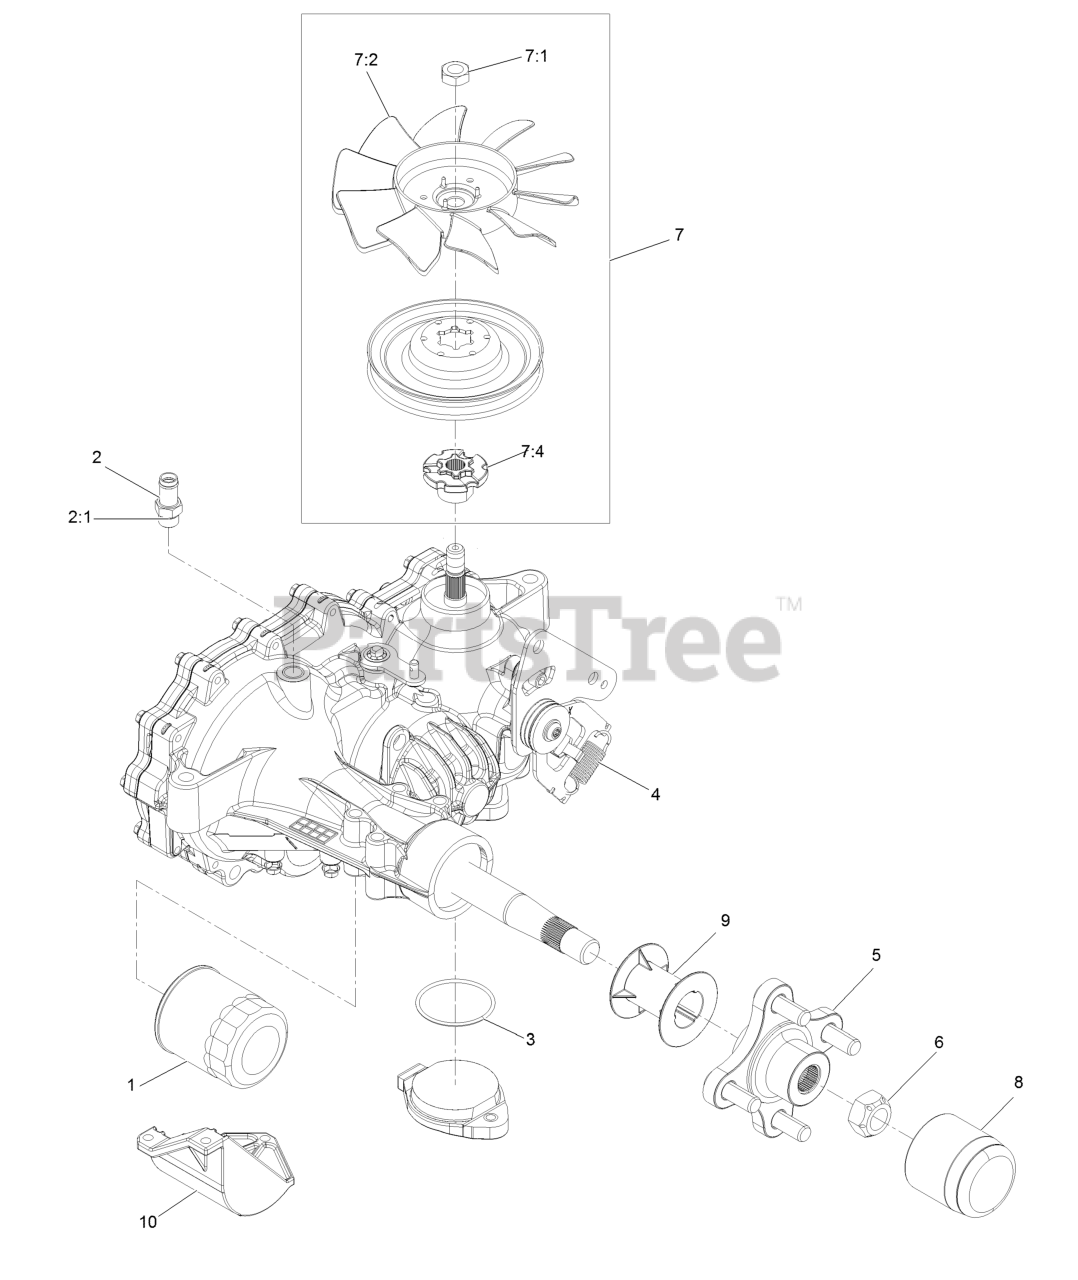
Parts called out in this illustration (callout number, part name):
1	Filter-Hydraulic
2	Adapter-Straight
2:1	O-Ring
3	O-Ring-Charge Seal Cover
5	Hub-Offset
6	Nut-Hub
7	Fan And Pulley Kit
7:4	Hub-Pulley
8	Cap-Axle, Long
9	Tube-Axle
10	Guard-Filter, RH
99	Brake Shaft Seal Kit
99	Seal Kit
